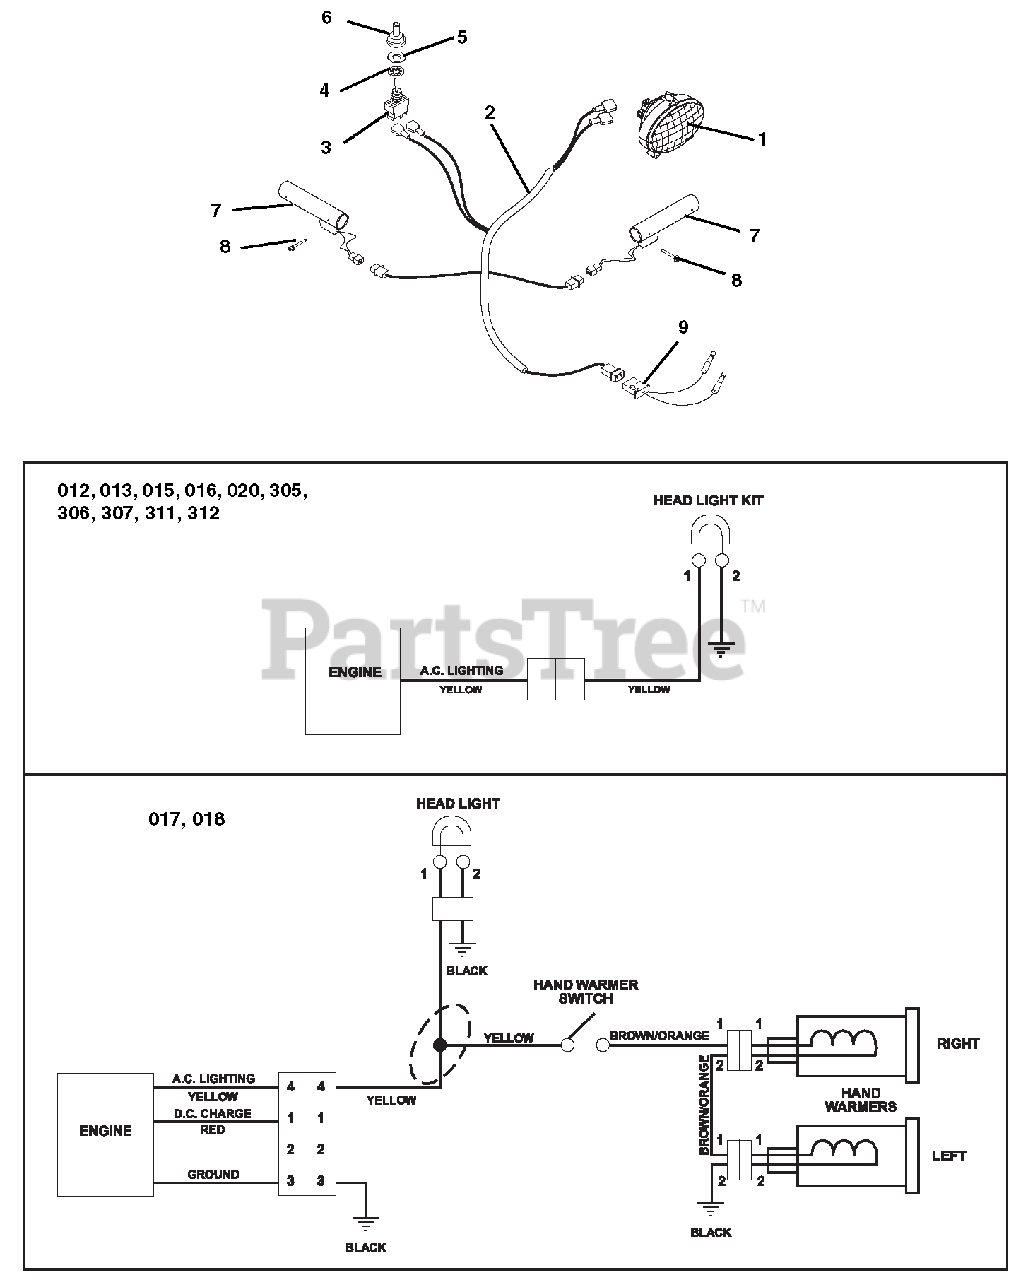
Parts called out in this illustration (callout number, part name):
1	LIGHT, HALOGEN ASSY.
1	LIGHT, HALOGEN ASSY 12W
2	HARNESS, WIRE-LIGHT
2	HARNESS, HEADLIGHT 2-PIN W/GRD
2	HARNESS, LIGHT&HW, 2 PIN W/GRD
3	SWITCH, ON/OFF
4	WSHR-LK-INT .563X.040 YWZC
5	WSHR-FL-STL .505X.875X.024 PL
6	BOOT, SWITCH
7	HEATED GRIP, MAGURA
8	RVT-POP #43 .125X.313 STL ZINC
9	HARNESS ADAPTER, SUBARU
